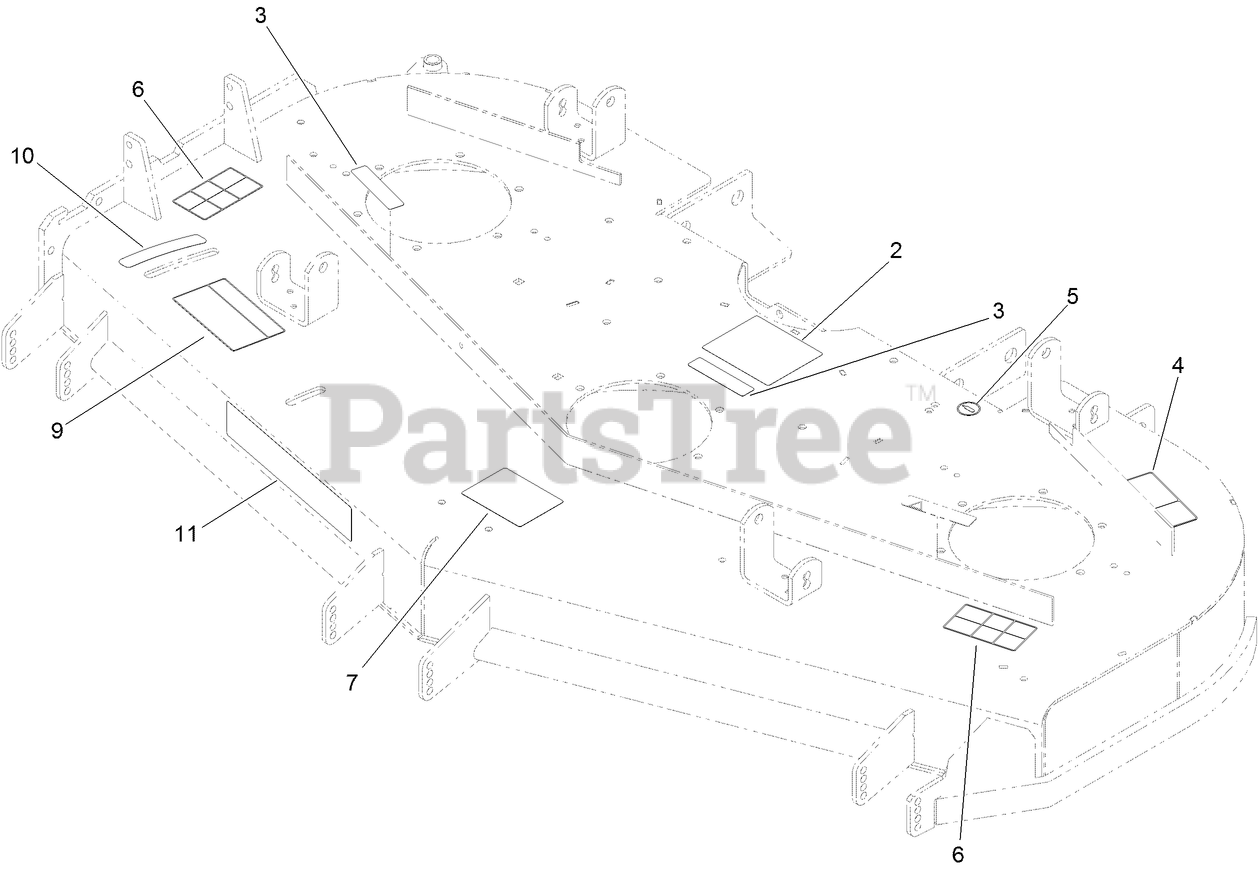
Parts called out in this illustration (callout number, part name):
2	DECAL-ROUTING, BELT
3	DECAL-WARNING
4	DECAL-TORQUE, BLADE BOLT
5	DECAL-GREASE
6	DECAL-DANGER
7	DECAL-SCALP, ANTI
9	DECAL-ADJUSTMENT, BAFFLE
10	DECAL-SETTING, BAFFLE
